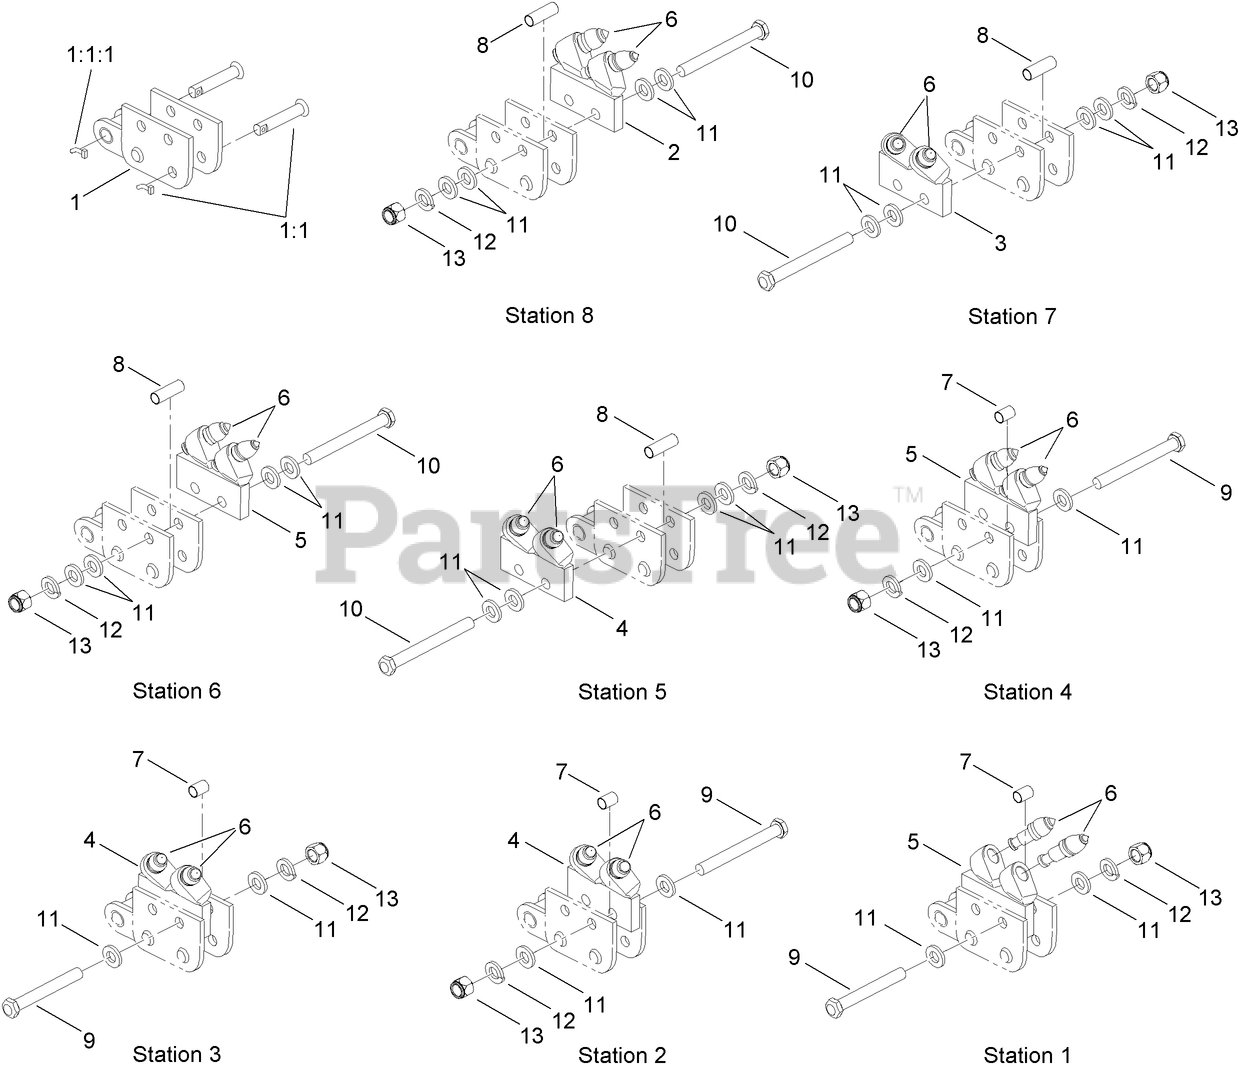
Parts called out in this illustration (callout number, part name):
1	CHAIN REPAIR LINK ASM
1:1	NOTCHED PIN AND KEEPER ASM
1:1:1	PIN-KEEPER
2	HOLDER-BIT, LH
3	HOLDER-BIT, RH
4	HOLDER-BIT, RH
5	HOLDER-BIT, LH
6	BIT-RETAINER, REAR
7	SPACER-TUBE, INSIDE ADAPTER
8	SPACER-TUBE, OUTSIDE MOUNT
9	BOLT-HH
10	BOLT-HH
11	WASHER-FLAT
12	WASHER-LOCK
13	NUT-LOCK
